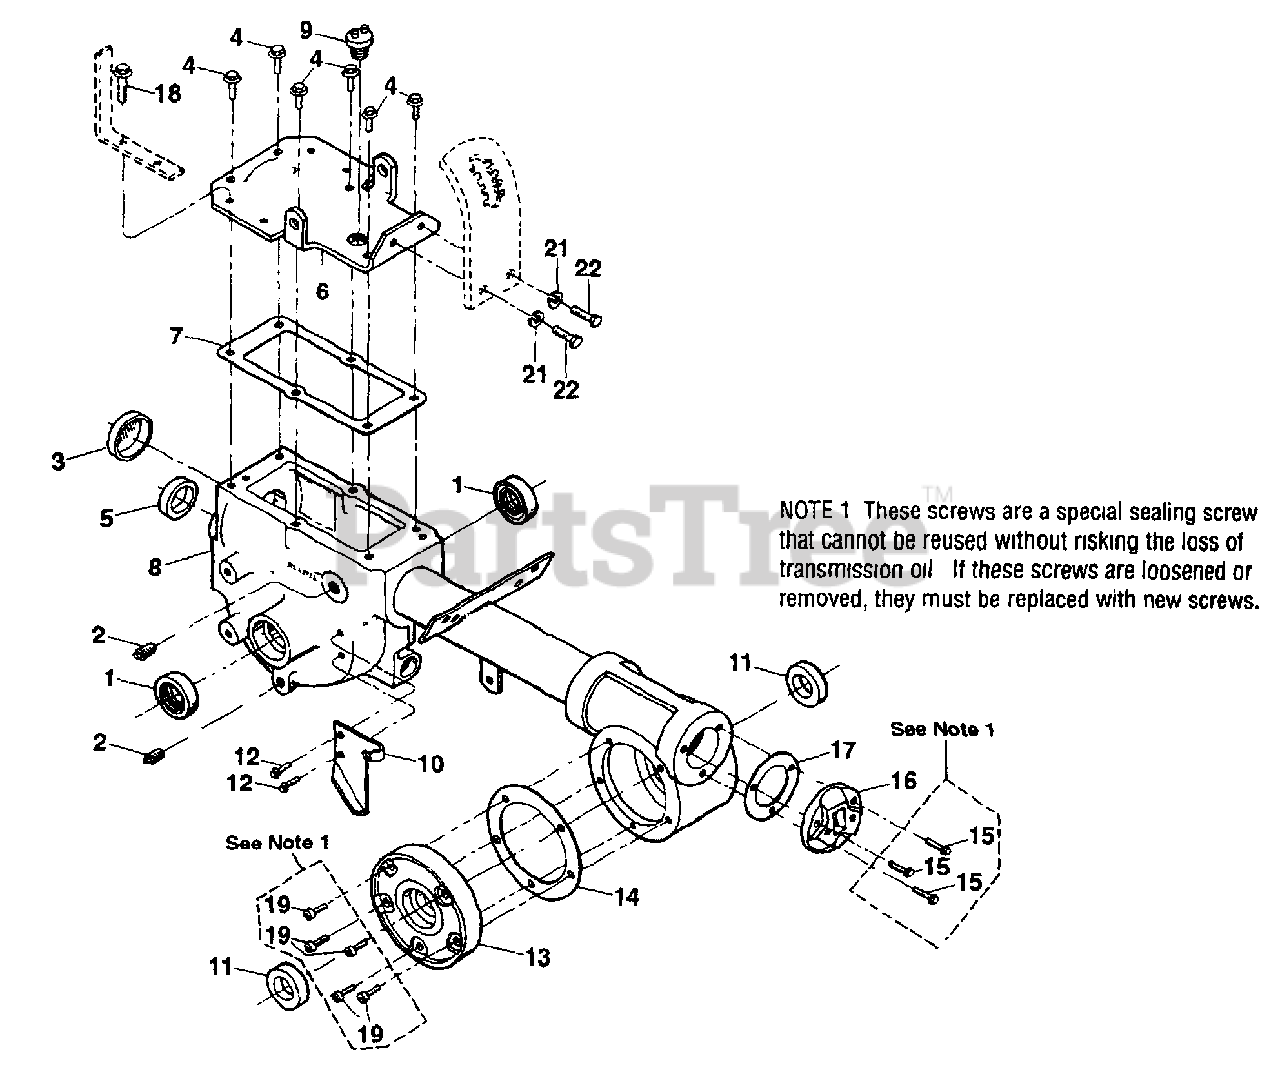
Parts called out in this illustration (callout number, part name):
1	Oil Seal (Double Lip), Wheel Shaft
2	Pipe Plug, 1/4,
3	Seal, Transmission Bore
4	Hex Flange Screw, 5/16-18 x 3/4
5	Oil Seal, Input Pinion Shaft
6	Transmission Cover
7	Gasket, Transmission Top Cover
8	Transmission Case Assy.
9	Plug
10	Mounting Plate, Wheel Drive Cable
11	Oil Seal, Tiller Shaft
12	Hex Flange Screw, 5/16-18 x 5/8
13	Tiller Housing Cover, left side
14	Gasket, Tiller Housing Cover, .010"
15	Screw Kit
16	Rear Bearing Cap
17	Gasket, Rear Bearing Cap, .010" Thick
18	Hex Flange Screw, 5/16-18 x 1
19	Screw Kit
21	Lockwasher, 3/8
22	Hex Hd. Screw, 3/8-16 x 3/4
